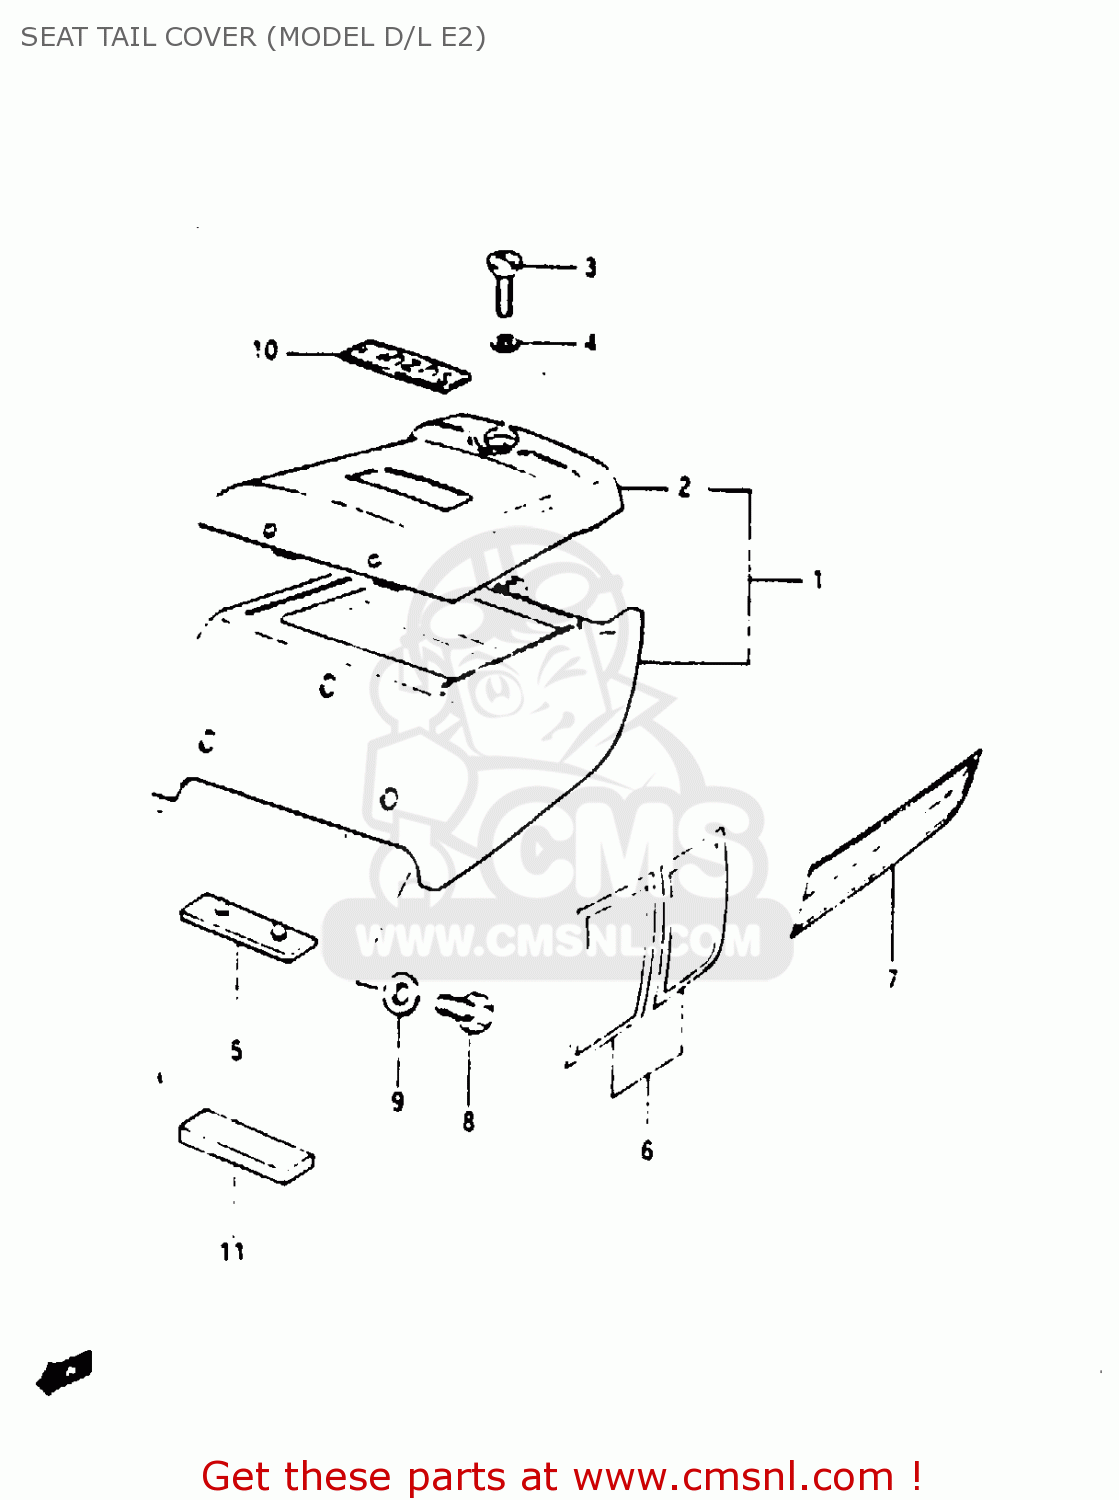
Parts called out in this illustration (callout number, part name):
1	COVER SET, TAIL (BLUE)
2	LID (BLUE)
3	KNOB,SEAT TAIL COVER
4	E RING
5	CUSHION
6	TAPE SET, SEAT TAIL COVER
7	TAPE SET, SEAT TAIL COVER
8	BOLT
9	WASHER
10	EMBLEM
11	CUSHION,SEAT TAIL
